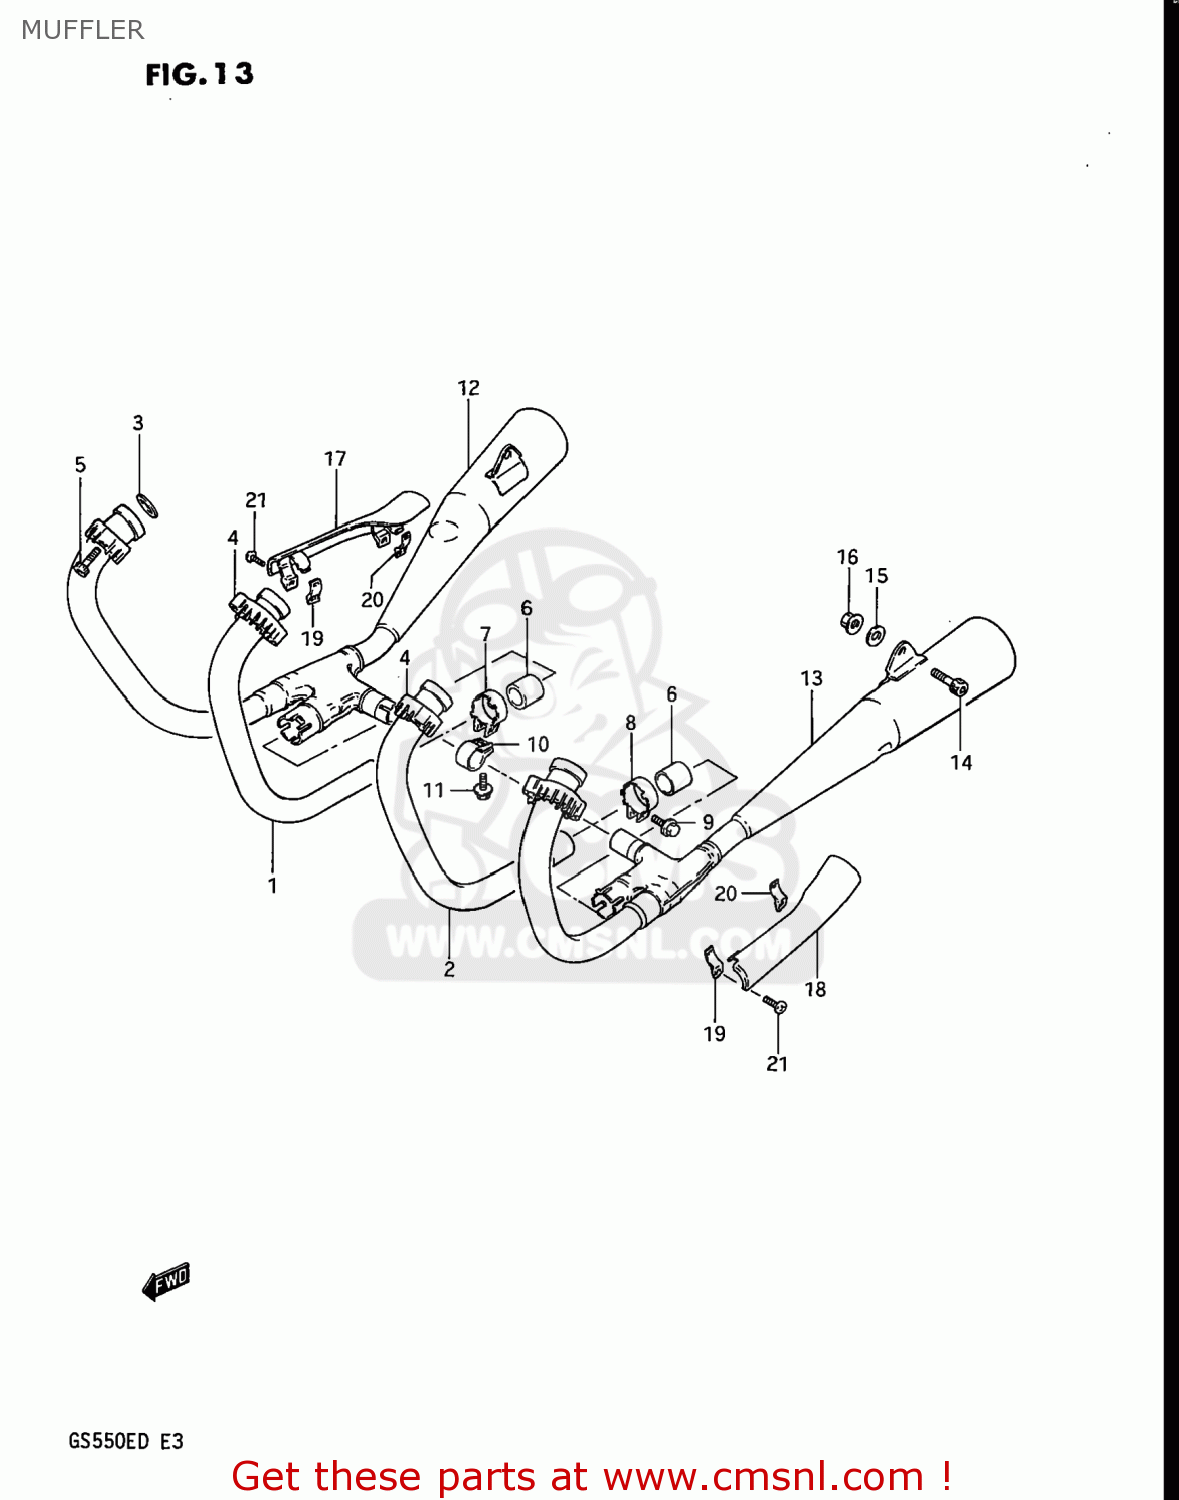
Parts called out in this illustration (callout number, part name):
1	PIPE,EXHAUST,CENTER,RIGHT
2	PIPE,EXHAUST,CENTER,LEFT
3	GASKET,EXHAUST PIPE (NAS)
4	CLAMP,EXHAUST PIPE
5	BOLT
6	CONNECTOR,MUFFLER
7	CLAMP,MUFFLER CONNECTOR
8	CLAMP,MUFFLER CONNECTOR
9	BOLT
10	CLAMP,EXHAUST
11	BOLT
12	MUFFLER
13	MUFFLER,LEFT
14	BOLT
15	WASHER(10.5X20X3.2)
16	NUT
17	COVER,MUFFLER
18	COVER,MUFFLER
19	CLAMP,MUFFLER COVER
20	CLAMP,MUFFLER COVER
21	SCREW
